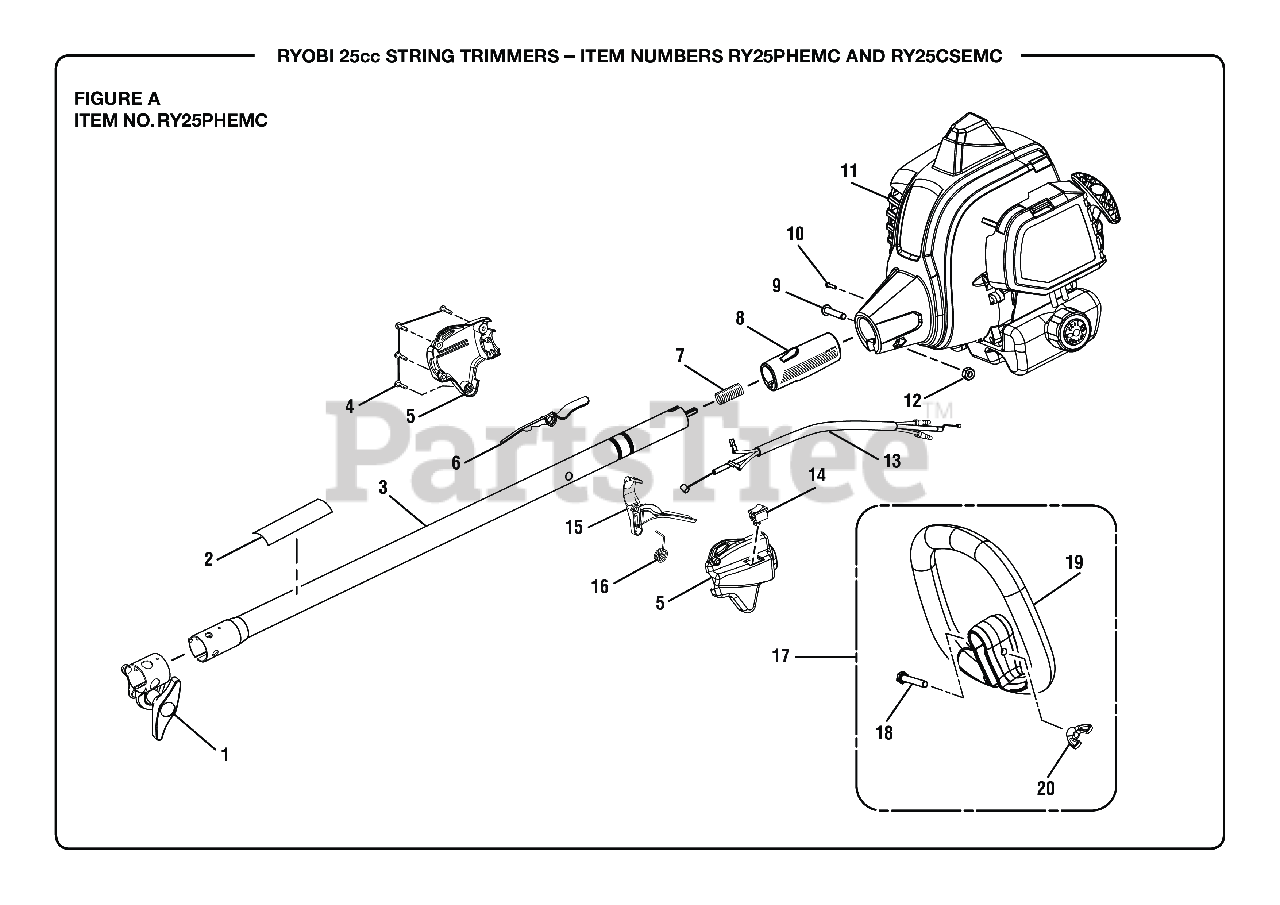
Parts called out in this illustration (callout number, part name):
1	Boom Clamp Assembly
2	Warning Icon Label
3	Upper Boom Assembly
4	Screw (M4 x 20 mm, T20 Torx Pan Hd. S.T.)
5	Control Handle Assembly (Inc. Key No. 6)
6	Trigger Lock
7	COMPRESSION SPRING
8	Rear Handle Grip
9	Screw (M6 x 30 mm, T27 Torx Button Hd.)
10	Screw (M4 x 8 mm, T25 Torx Pan Hd. T.F.)
11	Powerhead Assembly w/Labels
12	Hex Nut (M6.3 x 1)
13	Throttle Cable and Wire Assembly
14	Stop Switch (Momentary Contact)
15	Throttle Trigger
16	Torsion Spring (Throttle Trigger)
17	Auxiliary Handle Assembly
18	Screw (1/4-20 x 40 mm, Cap Hex Hd.)
19	Front Handle
20	Wing Nut (1/4-20, Plastic)
